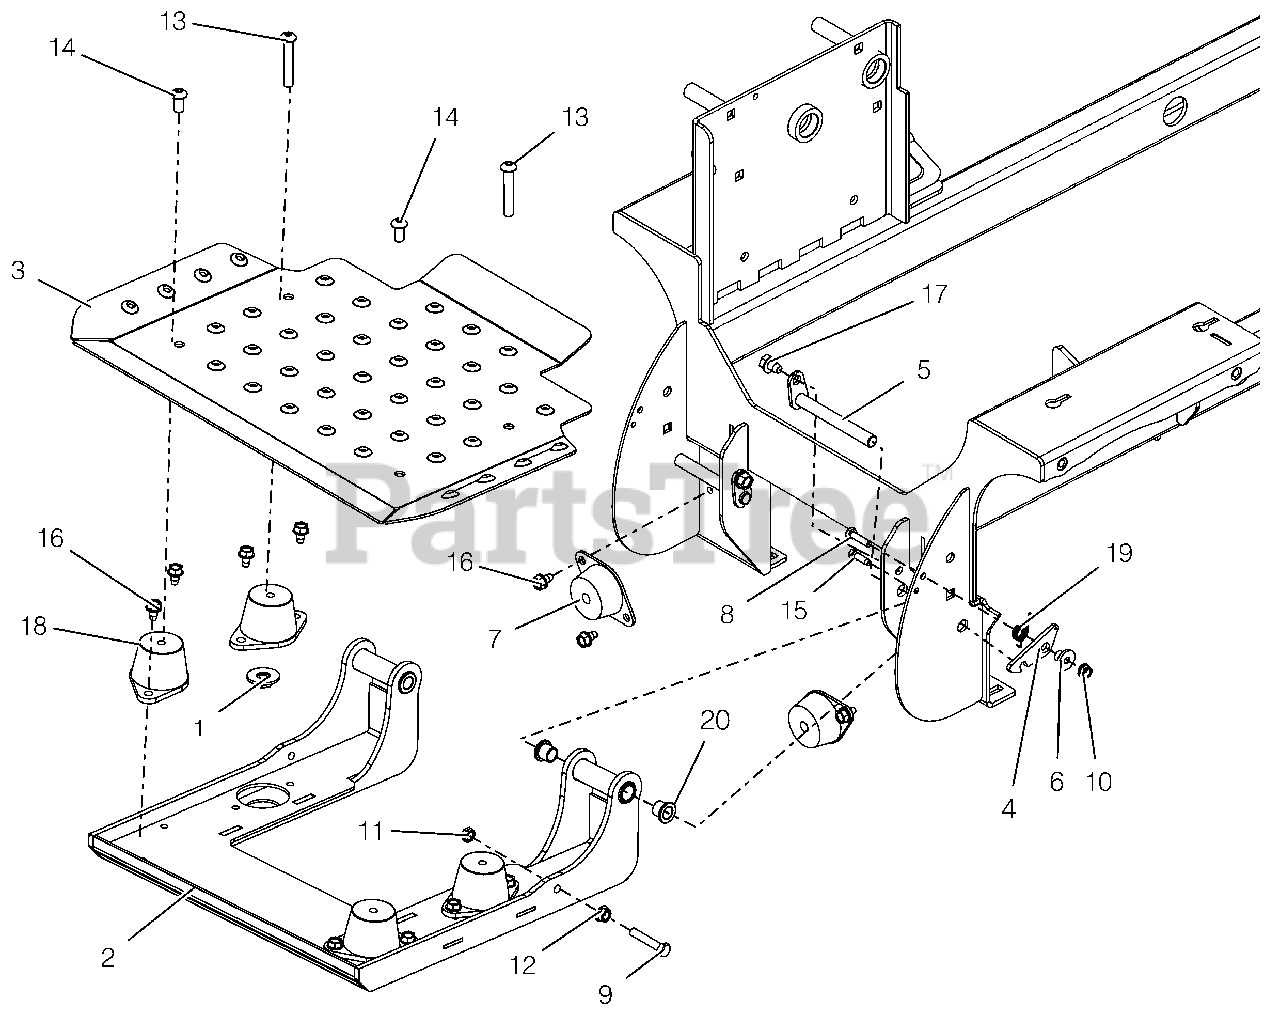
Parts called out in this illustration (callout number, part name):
1	WLDMT, SEAT RETAINER
2	WLDMT, OPERATOR PLATFORM
3	PLATE, OPERATOR PLATFORM
4	LATCH, PLATFORM
5	WLDMT, PIN
6	BUSH, FLG .26 .X .42 X .88
7	MOUNT, ENGINE, VIBRATION ISO
8	@BLT-HEX .25-20X1.00 GR5 YWZC
9	@BLT-HEX .31-18X1.75 GR5 YWZC
10	@NUT-LK-NYL-FLG .25-20 YWZC
11	@NUT-LK-CTR .31-18 YWZC
12	@NUT-SPNLK-FLG .312-18 YWZC
13	BLT-BTHD-SOCKET .38-16X2.25FTH
14	BLT-BTHD-SOCKET .38-16X.75
15	SCR-TAP-PM .25-20X.75 TR YWZ
16	@SCR-TAP .31-18X.50 HWH TR YWZ
17	@SCR-TAP .38-16X.50 HWH TR YWZ
18	MOUNT, ISOLATOR
20	BRG, FLG .500X.620X.500 BRNZ
